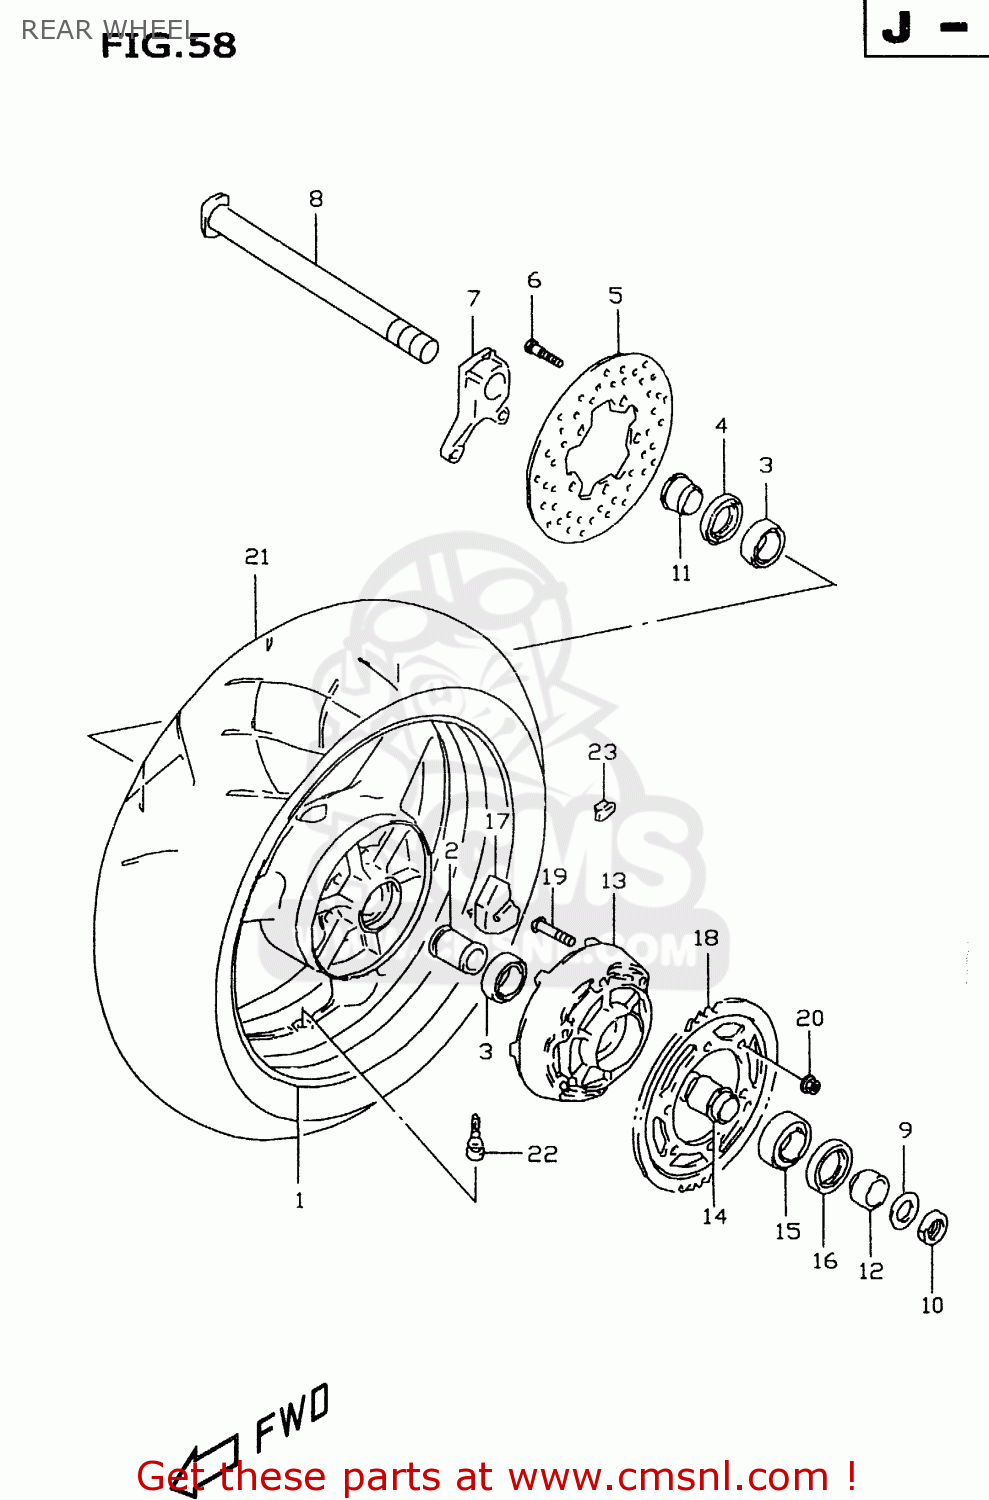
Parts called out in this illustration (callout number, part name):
1	WHEEL,RR(17XMT5.50)
2	SPACER COMP,REAR HUB B
3	BEARING(32X58X13)
4	SEAL,OIL(38X58X7)
5	DISC,RR BRAKE
6	BOLT 8X33
7	BRACKET,RR CALIPER
8	AXLE,RR
9	WASHER(25.2X42X3.2)
10	NUT
11	SPACER,RR AXLE,R
12	SPACER,RR AXLE,L
13	DRUM,REAR SPROCKET MOUNT
14	RETAINER,RR SPROCKET DRUM
15	BEARING
16	SEAL,OIL(39X65X7)
17	ABSORBER,RR HUB SHOCK
18	SPROCKET,RR(NT:45-525)
19	BOLT
20	NUT
21	TIRE,REAR 180/55 ZR17 (
22	VALVE ASSEMBLY,WHEEL,TR412
23	BALANCER,WHEEL (10G)
